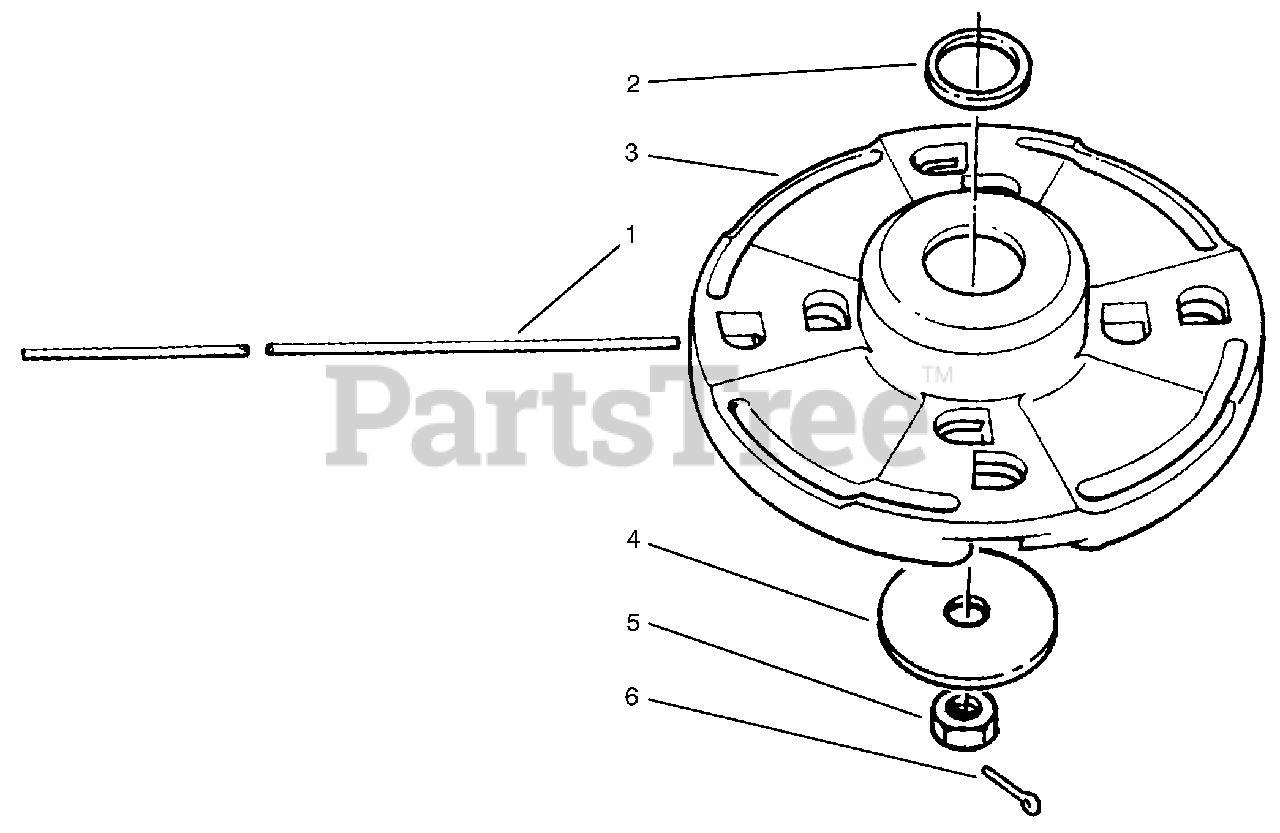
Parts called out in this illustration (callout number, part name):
1	Line-Cutting .105 Dia.
3	Cutter Head Assembly (Incl. Ref.#2)
4	Washer-Plate
5	Nut-L.H.
6	Pin-Cotter
